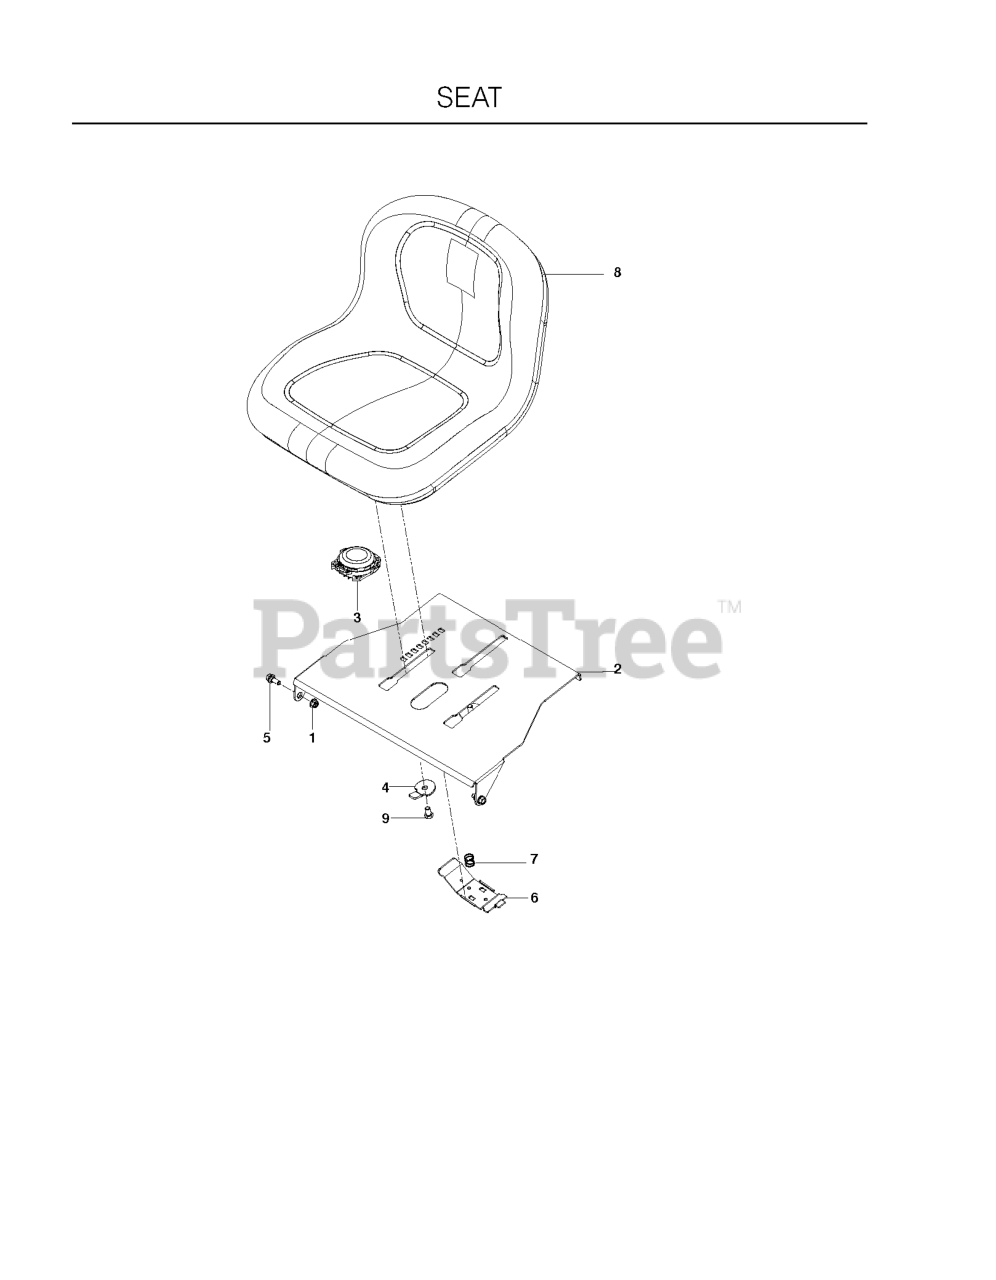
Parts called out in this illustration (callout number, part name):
1	5/16-18 NYLOC FLANGE NUT
2	PLATE, SEAT, ORG
3	SWITCH, SEAT N/C
4	STOP, SEAT, BLACK
5	BOLT, SHOULDER
6	HANDLE.SLIDE.SEAT.TEX.BLACK
7	SPRING.LATCH.SEAT.TEX
8	SEAT,BLACK W/ARMREST PROVISION
9	HCS 3/8-16 X 5/8 GR 5 ZD
